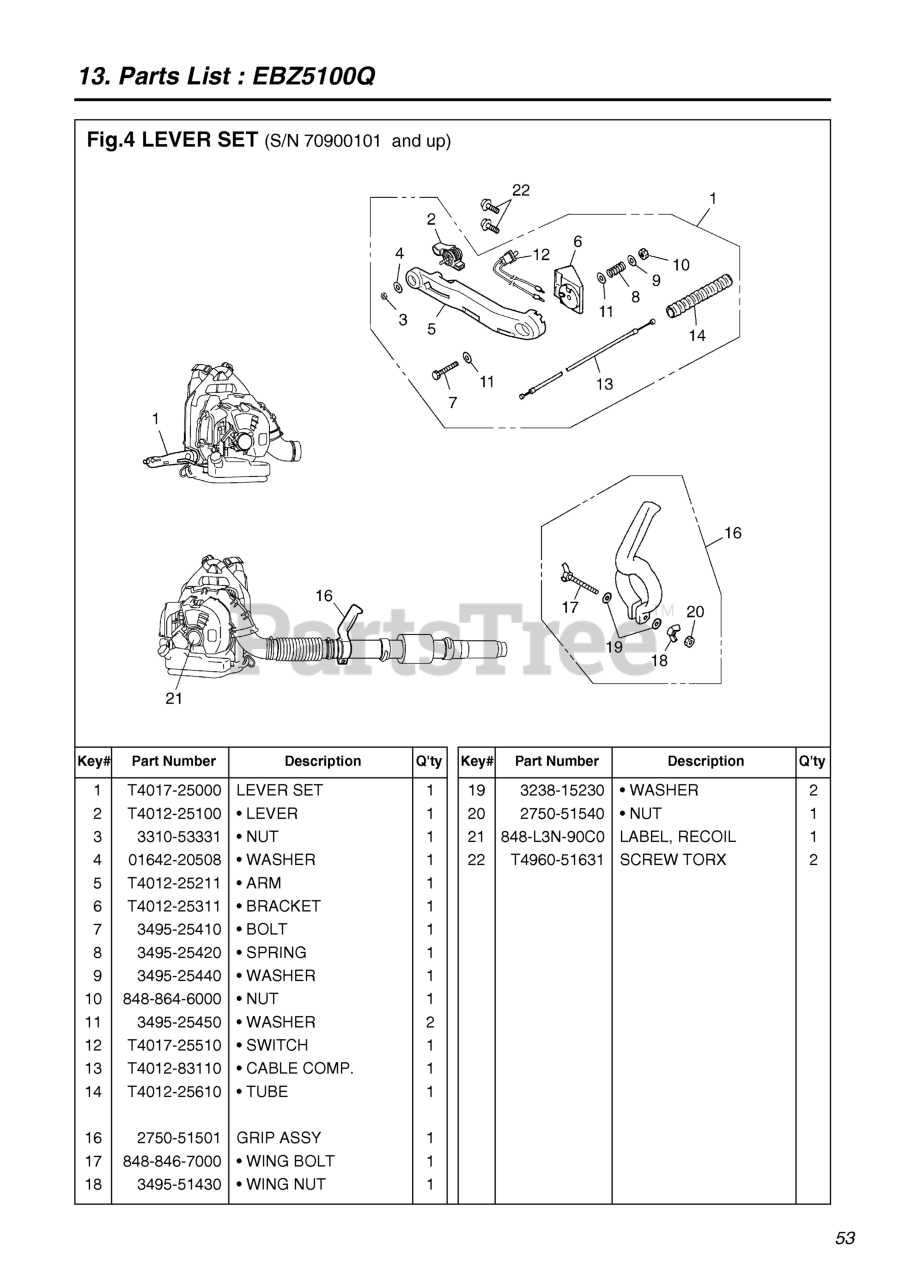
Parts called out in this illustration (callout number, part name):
1	LEVER SET
2	LEVER
3	NUT
4	WASHER
5	ARM
6	BRACKET
7	BOLT
8	SPRING
9	WASHER
10	NUT
11	WASHER
12	SWITCH
13	CABLE COMP
14	TUBE
16	GRIP ASSY
17	WING BOLT
18	WING NUT
19	WASHER
20	NUT
21	LABEL, RECOIL
22	SCREW TORX
